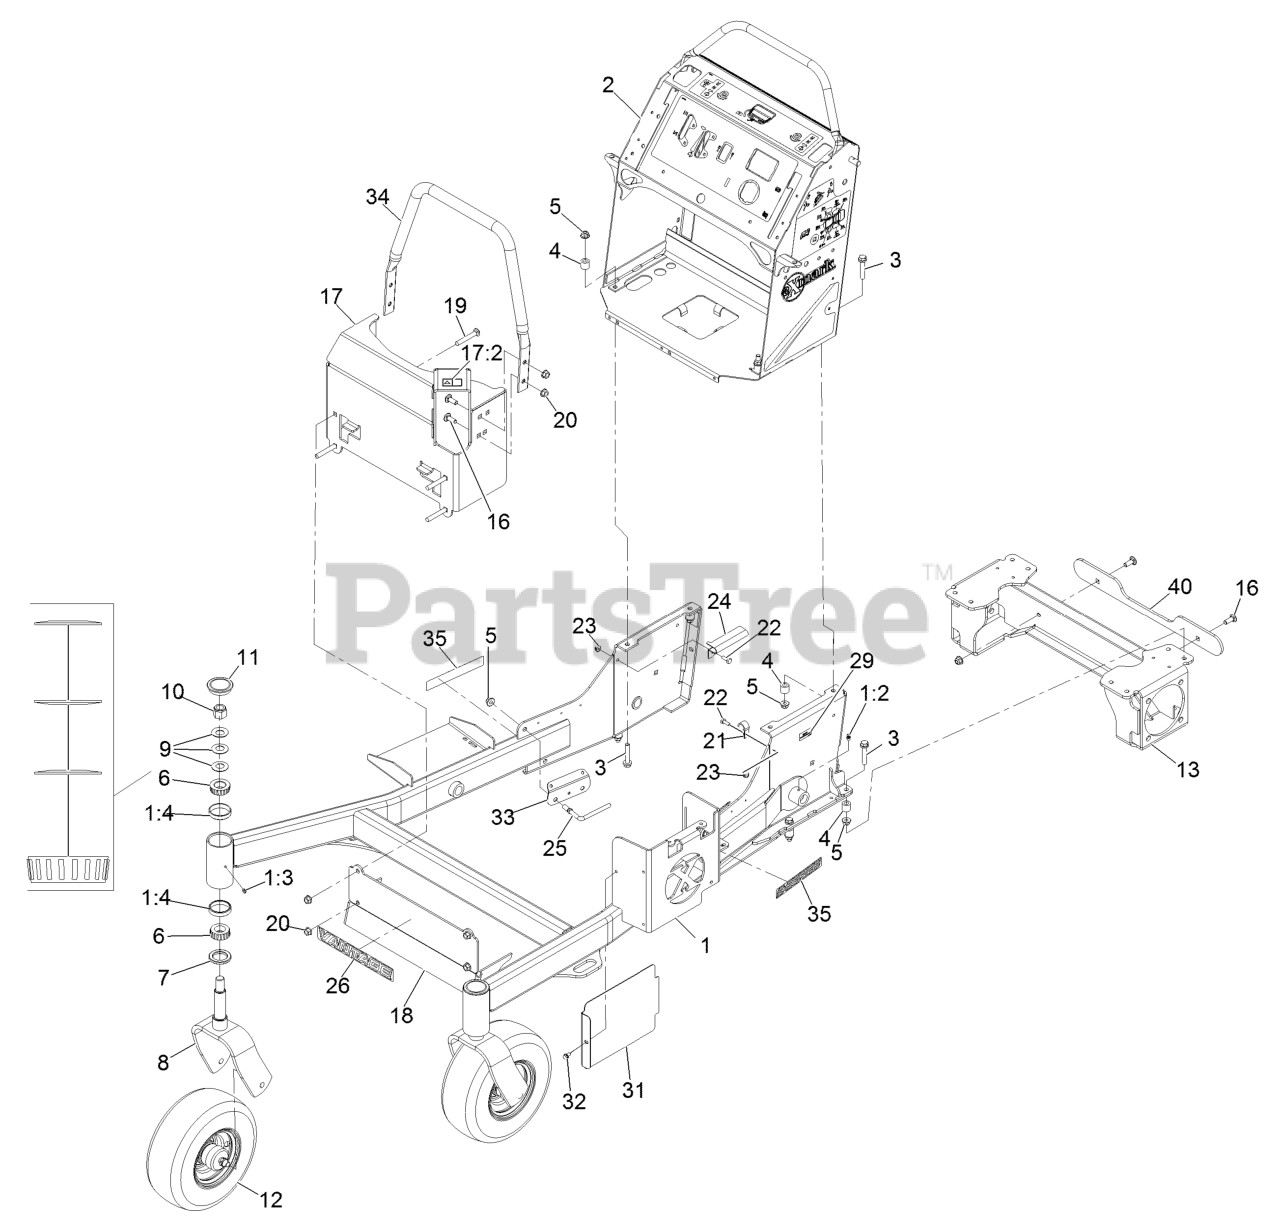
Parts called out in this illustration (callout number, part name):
1	Front Frame ASM
1:2	Zerk 1/4-28 Str Thrd Forming
1:4	Cup-Bearing Tapered Roller
2	Control Tower ASM
3	Screw-HHF
5	Nut-Flange, NI
6	Bearing-Roller, Tapered
7	Seal-Grease
8	Fork-Caster
9	Washer-Bellville
10	Nut-Lock, NI
11	Cap-Grease
12	Wheel/Tire And Bearing ASM
13	Motor Frame Weldment black]
16	Screw-CARR
17	ASM, Muffler Guard W/ Decal
17:2	Decal-Warning
18	Panel-Guard
19	Bolt-Carriage 3/8-16 X 2 1/2
20	Nut-3/8-16 Flanged Side Lock
21	Clamp-Cable
22	Screw-HH 1/4-20 X 3/4
23	Nut-Nyloc 1/4-20 Flg
24	Bracket-Hose, Fuel (Double)
25	Guide-Hose, Support
26	Decal-Vantage Logo
29	Decal-Patent
31	Shield-Heat, Tall
32	Screw-HWH 1/4-20 X 1/2 Taptite
33	Guard-Hose
34	Tube-Guard
35	Decal-S-Series
40	Plate, Bumper Spacer
